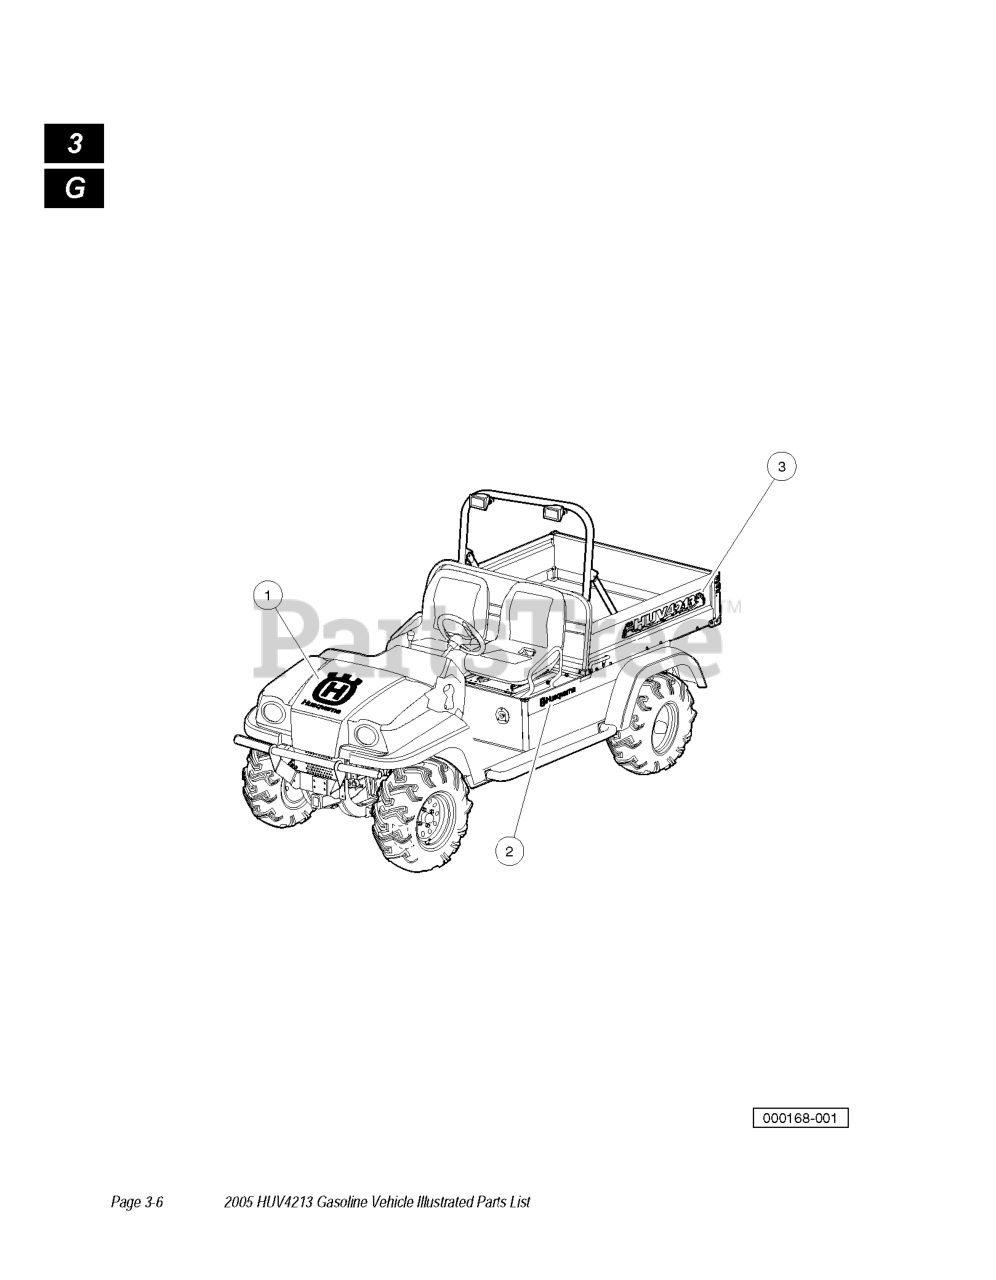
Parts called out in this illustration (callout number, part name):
1	DECAL HOOD
2	DECAL SIDE PANEL
3	DECAL, BED, HUV4220
